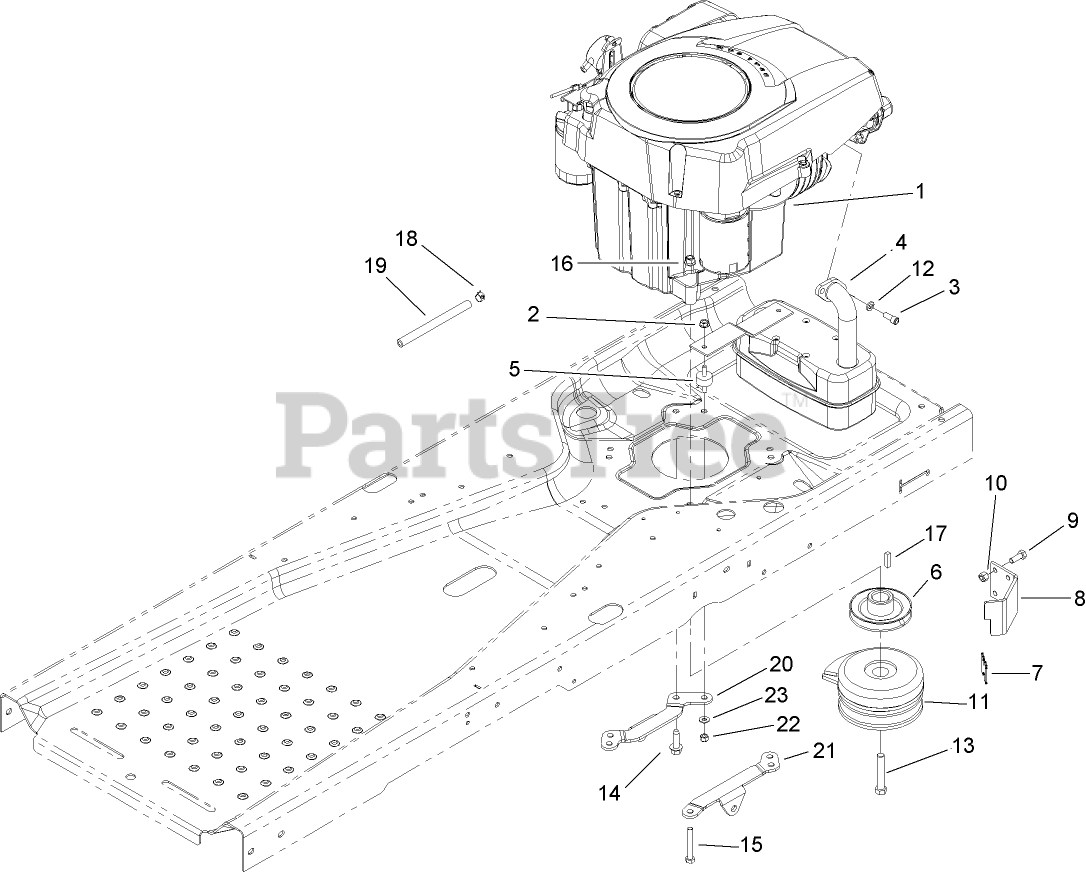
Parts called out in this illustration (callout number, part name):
1	Loose Parts Package
2	NUT-HF
3	SCREW-HSH
5	ISOLATOR
8	STOP-CLUTCH
9	SCREW-HH
10	NUT-LOCK, NI
11	CLUTCH-ELECTRIC
12	WASHER-LOCK
13	SCREW-HH
14	SCREW-THD
15	SCREW-HH
16	NUT-LOCK, NI
18	CLAMP-HOSE
19	HOSE-FUEL
20	SUPPORT-HYDRO, RH
21	SUPPORT-HYDRO, LH
22	NUT-LOCK, NI
23	WASHER-FLAT
